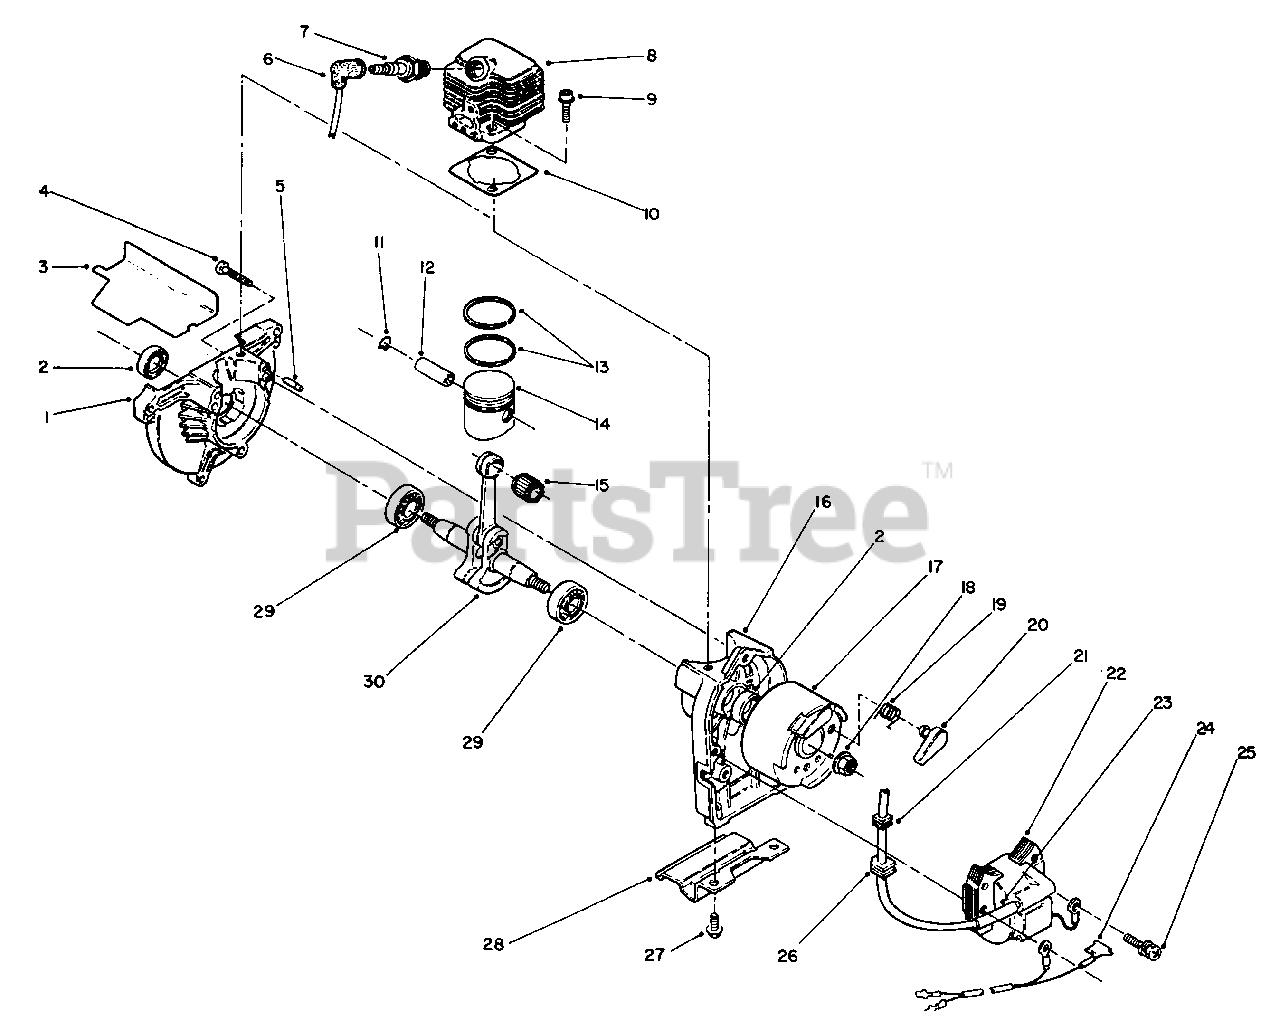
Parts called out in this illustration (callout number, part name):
1	Case-Drive
2	Seal-Oil
3	Gasket-Insulator
4	Screw-Pan Hd.
5	Pin-Dowel
6	Boot-Plug
7	Plug-Spark
8	Cylinder Head
9	Bolt-Cylinder Head
10	Gasket-Cylinder Head
11	Clip-Piston Pin
12	Pin-Piston
13	Piston Ring
14	Piston Assembly (Incl. Ref. #12)
15	Bearing-Needle
16	Case-Starter
17	Flywheel Assembly (Incl. Ref. #19 & 20)
18	Nut-Conical
19	Spring-Return
22	Coil-Ignition
23	Tube-Insulator
24	Wire Assembly
25	Bolt/Washer
27	Screw/Washer
29	Bearing-Main
30	Crankshaft Assembly
